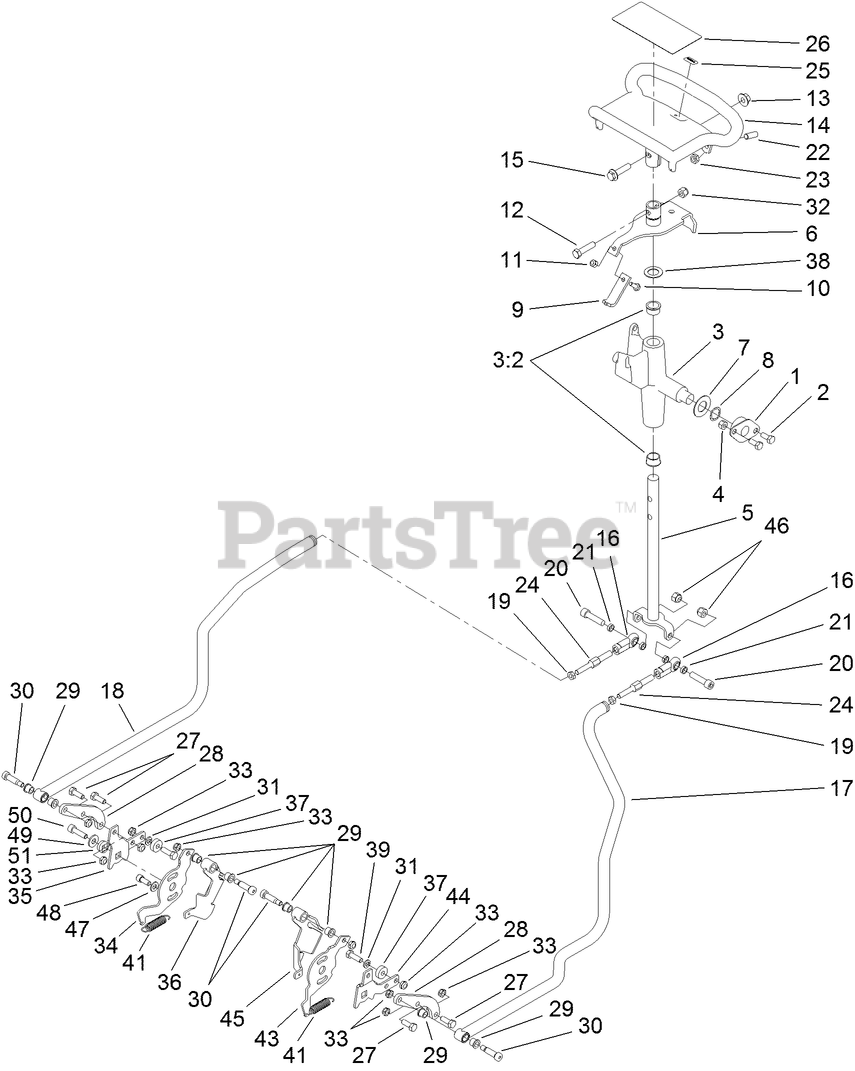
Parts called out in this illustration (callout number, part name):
1	BUSHING
2	SCREW-HH
3	CONTROL SUPPORT ASM
3:2	BEARING-FLANGE
4	NUT-LOCK, NI
5	ROD-DRIVE
6	LEVER-PIVOT
7	WASHER-FLAT
8	WASHER-SPRING, WAVE
9	PLATE-NEUTRAL
10	SCREW-HH
11	NUT-LOCK, NI
12	SCREW-HH
13	NUT-FLANGE
14	HANDLE-CONTROL
15	SCREW-HHF
16	JOINT-BALL END, LH
17	ROD-CONTROL,
18	ROD-CONTROL, RH
19	NUT-JAM
20	SCREW-HSH
21	SPACER-PLATE, RETAINING
22	SCREW-SET
23	NUT-JAM
24	LINK-CONTROL, ADJUSTMENT
25	DECAL
26	DECAL-TRACTION
27	SCREW-HH
28	PLATE-ADAPTER, CONTROL, RH
29	BUSHING-FLANGE
30	BOLT-SHOULDER
31	WASHER-LOCK
32	NUT-LOCK, NI
33	NUT-LOCK, NI
34	PLATE-BASE, RH
35	PLATE-ARM, RETURN
36	PIVOT-RH
37	BEARING-BALL
38	WASHER-THRUST
39	SCREW-HH
41	SPRING-EXTENSION
43	PLATE-BASE, LH
44	PLATE-ARM, RETURN, LH
45	PIVOT-LH
46	NUT-LOCK, NI
47	WASHER-BELLEVILLE
48	SCREW-HSH
49	WASHER-FLAT
50	SCREW-HSH
51	LOCK-TRUNION
